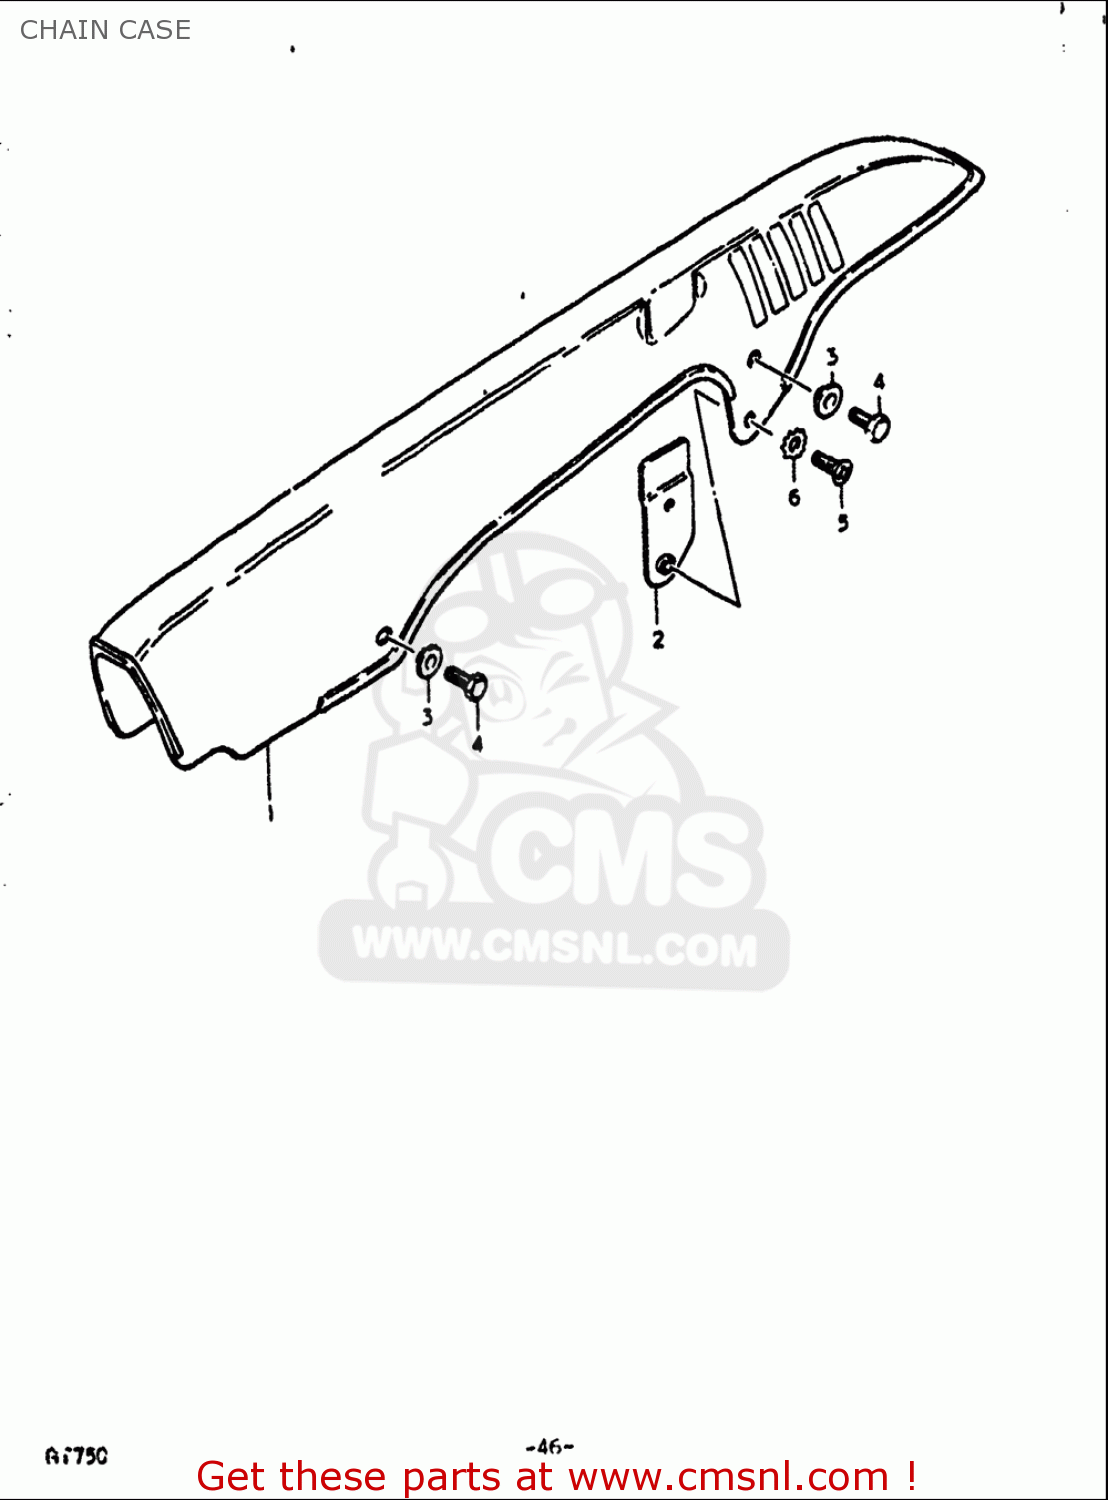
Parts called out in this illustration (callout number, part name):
3	WASHER
4	BOLT(6X8)
5	SCREW
6	LOCK WASHER
